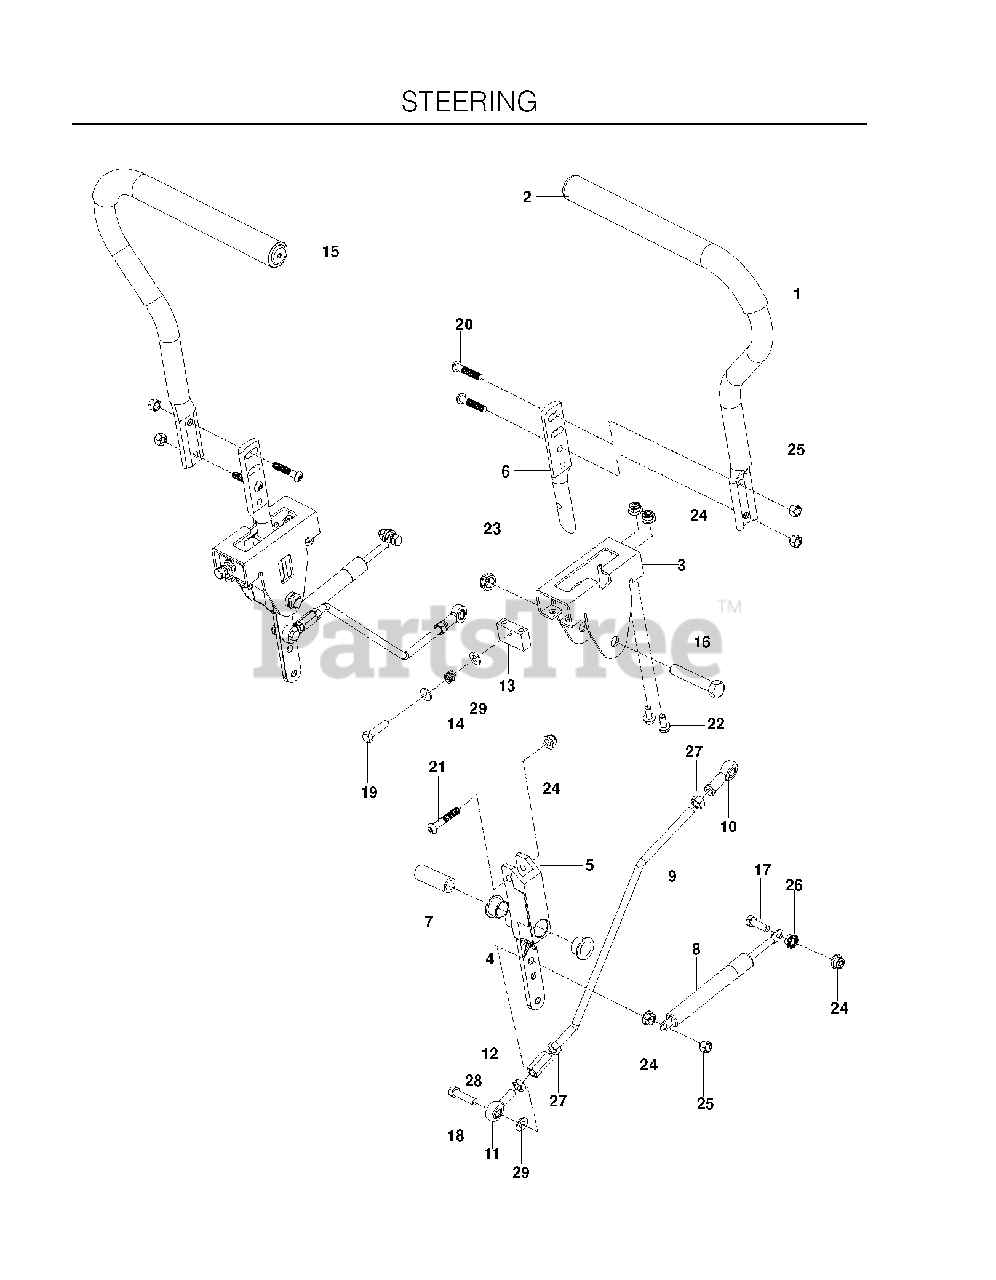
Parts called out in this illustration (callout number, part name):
1	LEVER ASM
2	GRIP, DRIVE LEVER
3	BRACKET, CONTROL
4	BEARING, FLANGE
5	LEVER CONTROL PIVOT
7	SPACER, PIVOT CONTROL
8	DAMPENER
9	ROD, MOTION CONTROL
10	RH ROD END
11	ROD END LH
12	ROD END COUPLER
13	BLOCK, TRACKING
15	END PLUG 15/16` (BLACK)
16	HCS 1/2C X 2 3/4
17	HCS 5/16C X 1
18	HCS 5/16-18X1-3/4 TPBLT
19	CAPSCREW 5/16 X 1/1/2 HEX HEAD
20	SCREW 5/16-18 X 1 BTN-HD
22	HHFS 5/16-18 X 3/4
23	NUT 1/2-13 HEX JM NYL
24	5/16-18 NYLOC FLANGE NUT
25	NUT 5/16 NYLOC
26	NUT 5/16C WHIZ
27	NUT 5/16F
28	NUT 5/16F LEFTHAND
29	FLAT WASHER 5/16 SAE
